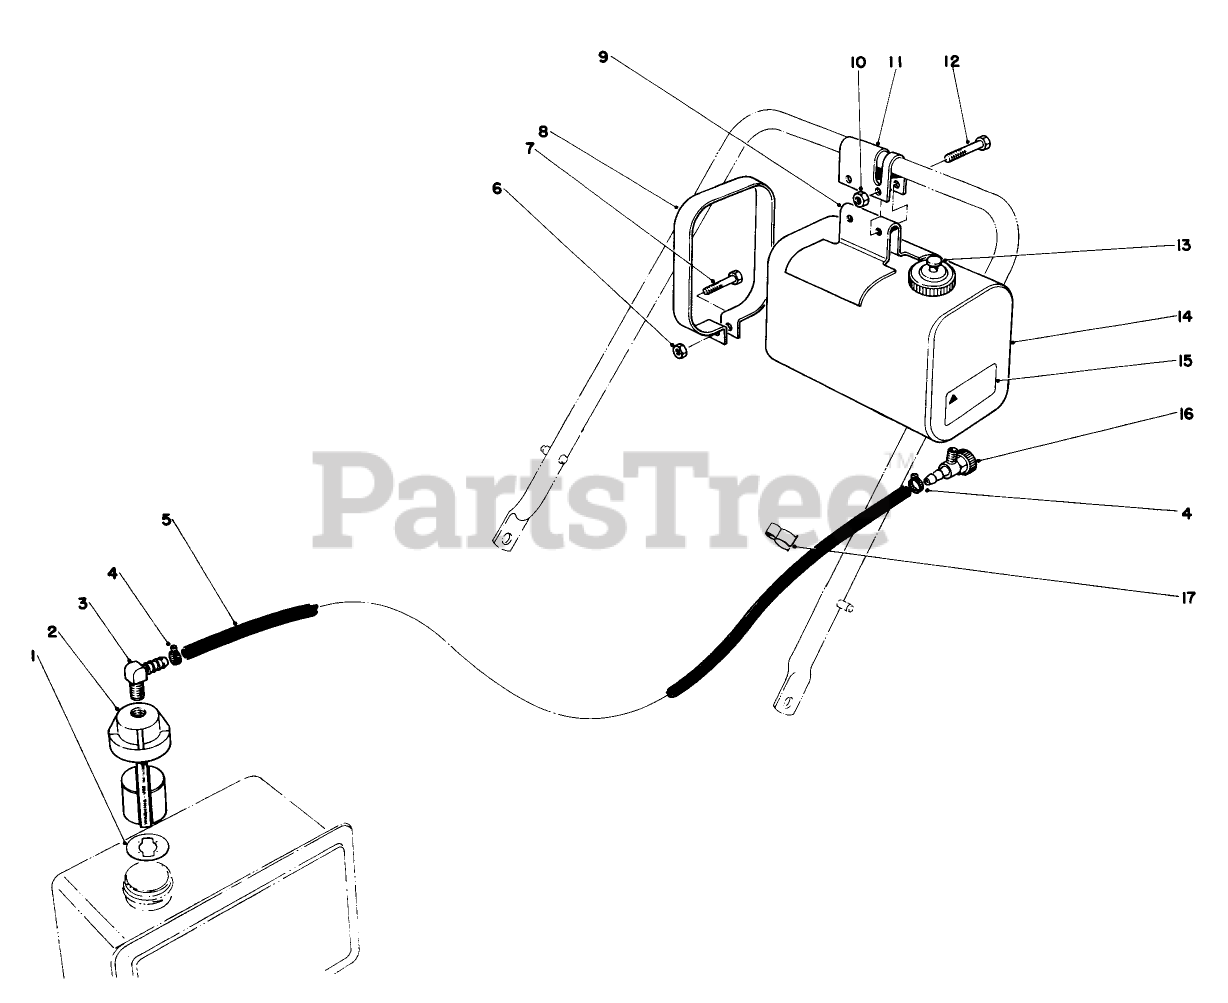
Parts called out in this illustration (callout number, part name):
2	FUEL CONT VALVE ASM
3	CONNECTOR-HOSE
4	CLAMP-HOSE
7	SCREW-HH
12	SCREW-HH
